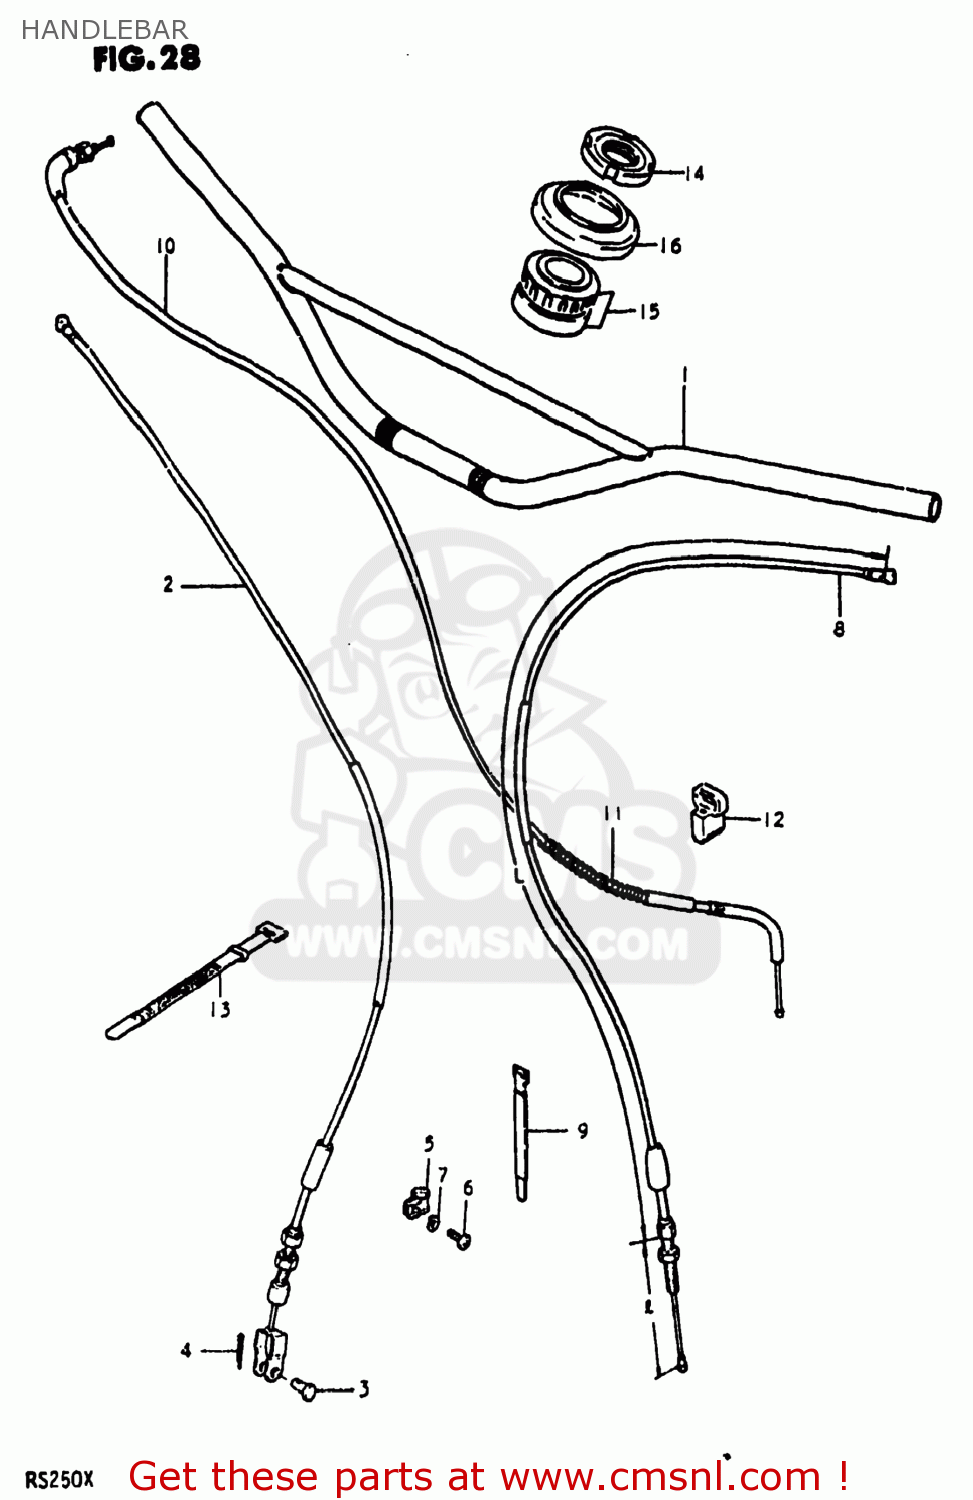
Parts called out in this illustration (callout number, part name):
1	HANDLEBAR
2	CABLE ASSEMBLY,FRONT BRAKE
3	PIN(L:17.5)
4	PIN
5	GUIDE,CABLE
6	SCREW
7	LOCK WASHER
8	CABLE ASSY,CLUTCH
9	CLAMP
10	CABLE ASSEMBLY,THROTTLE
11	PROTECTOR,CABLE
12	GUIDE,CABLE
13	CLAMP(L:120)
14	NUT,STEERING STEM(25X44X10)
15	TAPER,ROLLER BEARING
16	DUST SEAL,STEERING,UPPER
